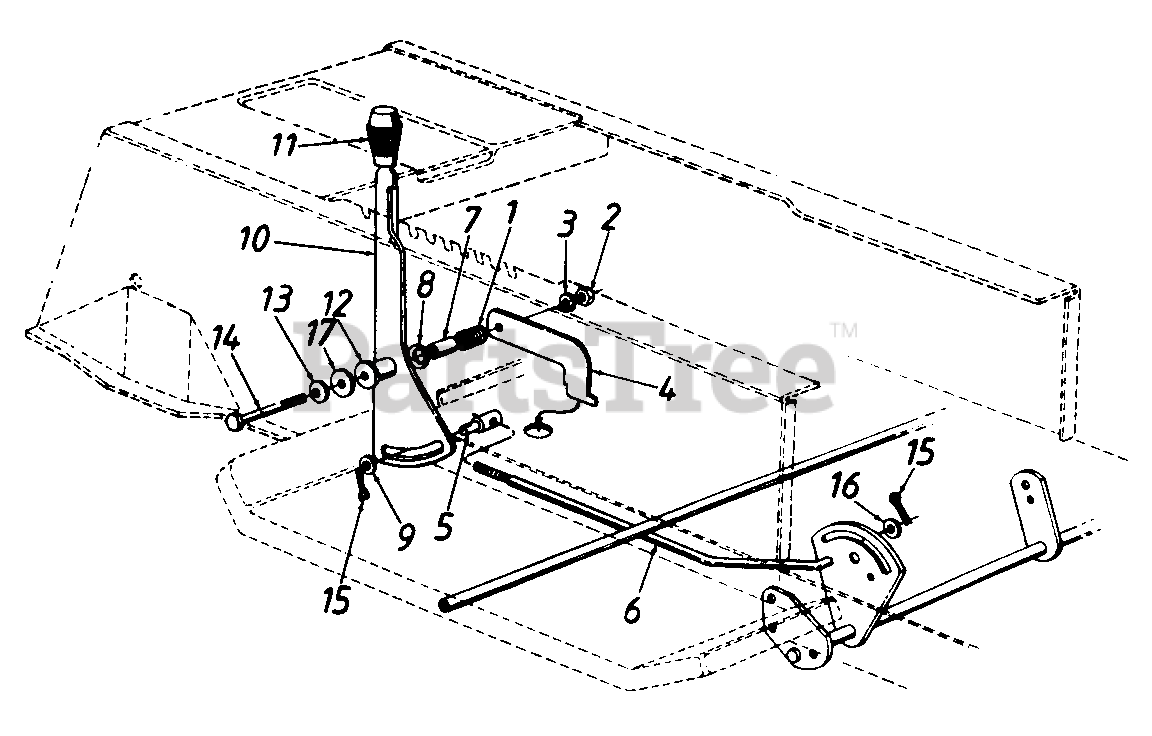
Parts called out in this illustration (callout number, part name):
1	Compression Spring
2	Hex Nut 5/16-18 Thd.
3	L-Wash. 5/16" I.D.
4	Shift Lever Support
5	Ferrule 3/8-24 Thd.
6	Speed Control Rod
7	Spacer 1.56" Lg.
8	Bell-Wash .505" I.D. x 1"
9	Fl-Wash .385" I.D. x .87"
10	Speed Selector Lever
11	Shift Knob
12	Spacer 1.46" Lg.
13	Bell-Wash .345" I.D. x .88"
14	Hex Bolt 5/16-18 x 3.25" Lg.
15	Cotter Pin 3/32" Dia. x 1"
16	Fl-Wash .469" I.D. x .88"
17	Fl-Wash .34" I.D. x 2.25"
